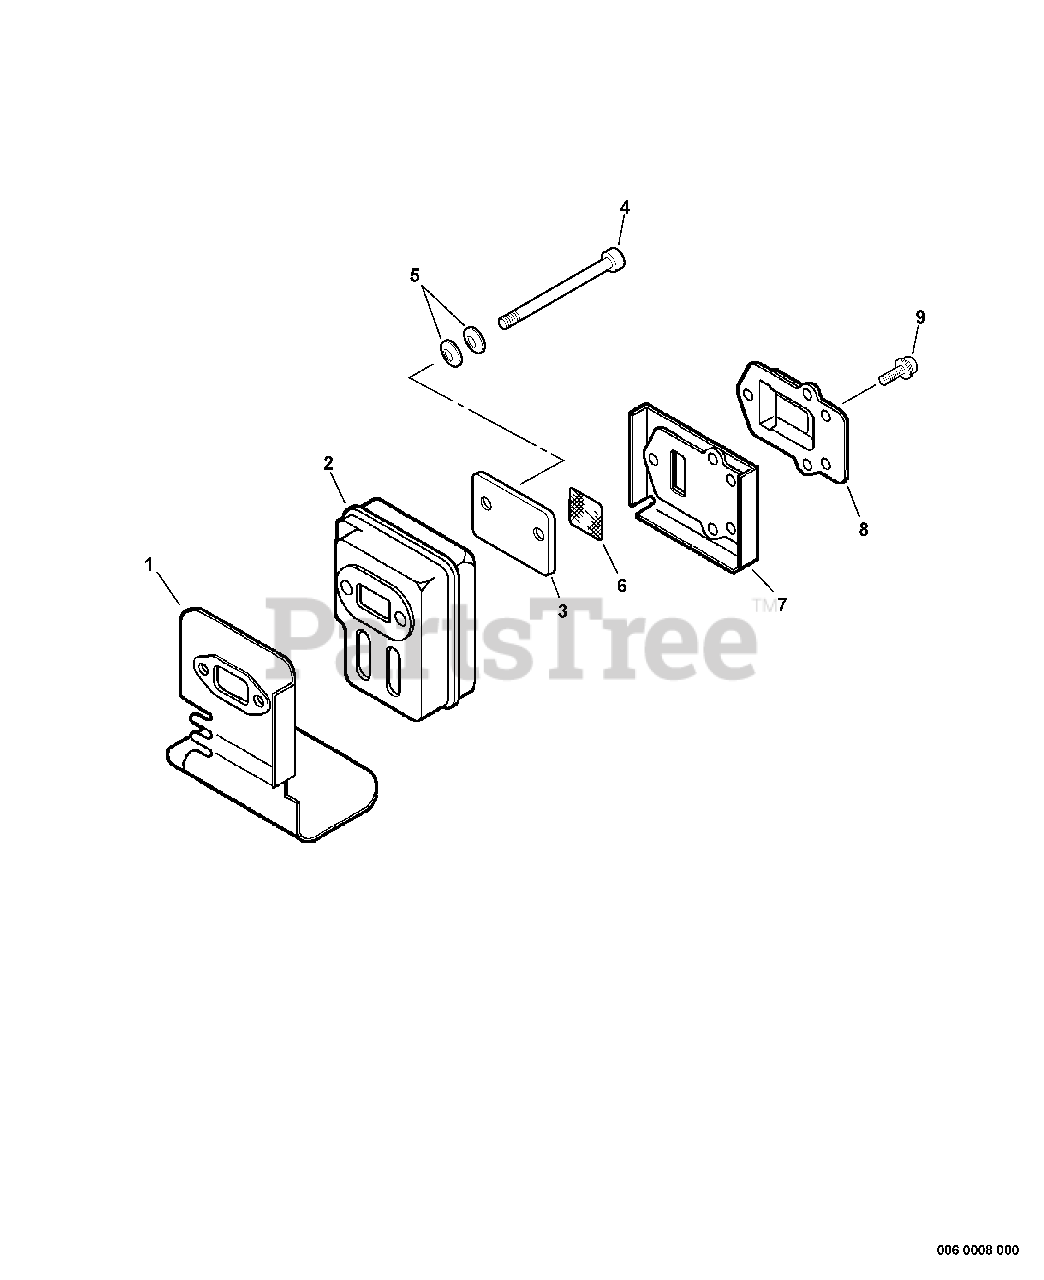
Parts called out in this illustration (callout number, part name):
1	SHIELD, EXHAUST
2	MUFFLER
4	SCREW - 5X55
5	WASHER - CONICAL
6	SCREEN, SPARK ARRESTOR
7	GASKET, EXHAUST
8	GUIDE, EXHAUST
9	SCREW - 4X10
